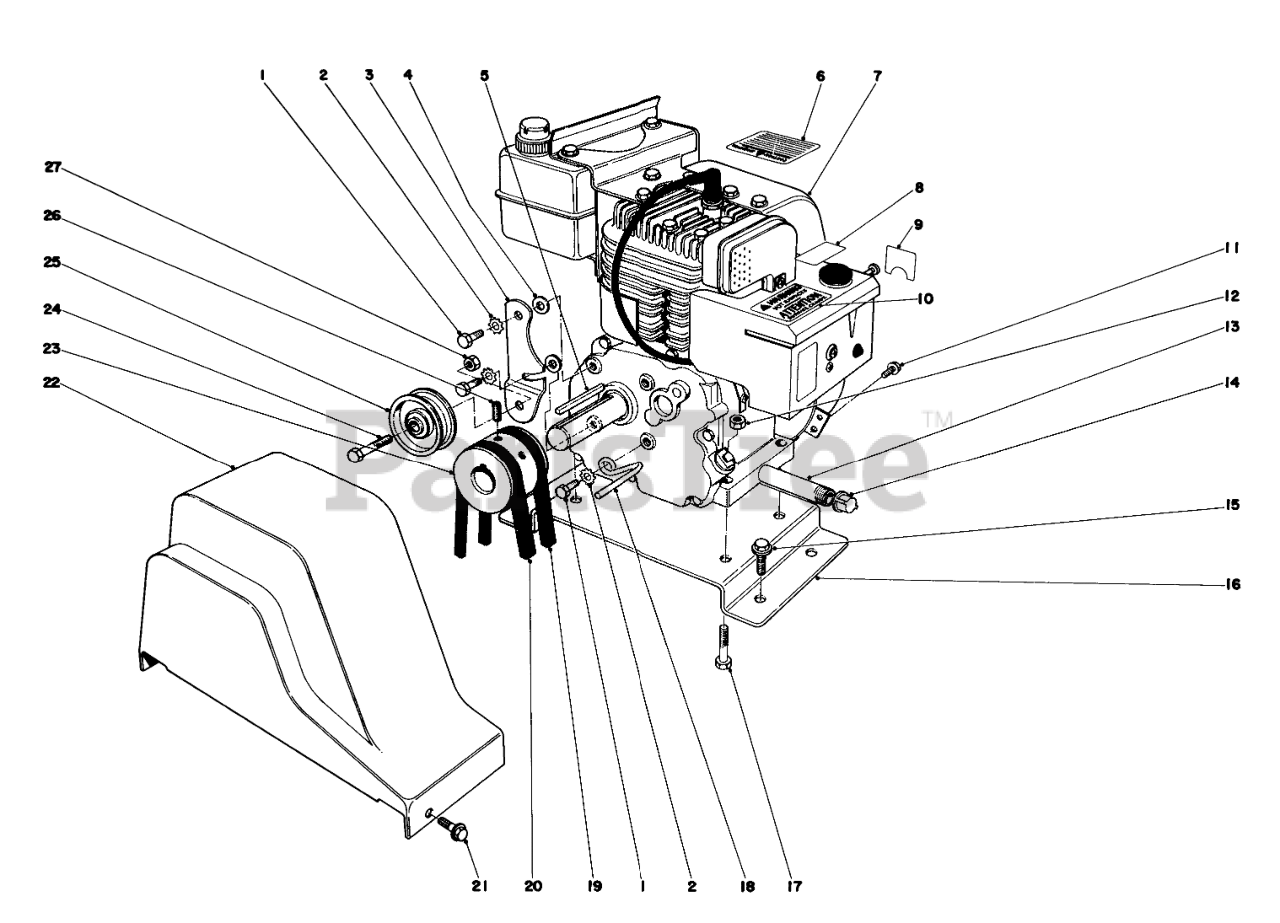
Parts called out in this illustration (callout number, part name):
1	SCREW-HH
2	WASHER-LOCK
3	ENGINE IDLER ARM
4	WASHER-PLAIN
6	HAZARDS CAUTION DECAL
7	Engine
8	Decal-Primer
9	CHOKE DECAL
10	Decal
11	SCREW
12	NUT-LOCK, NI
13	NIPPLE-PIPE
14	CAP-PIPE
15	SCREW-HHFTF
16	ENG MTG PLATE R
17	SCREW-HH
18	BELT RETAINER
19	V-BELT
20	V-BELT
21	SCREW-HWH
22	BELT GUARD
23	ENGINE PULLEY
24	SCREW-HH
25	PULLEY-IDLER
26	Screw-Set
27	NUT-HEX
